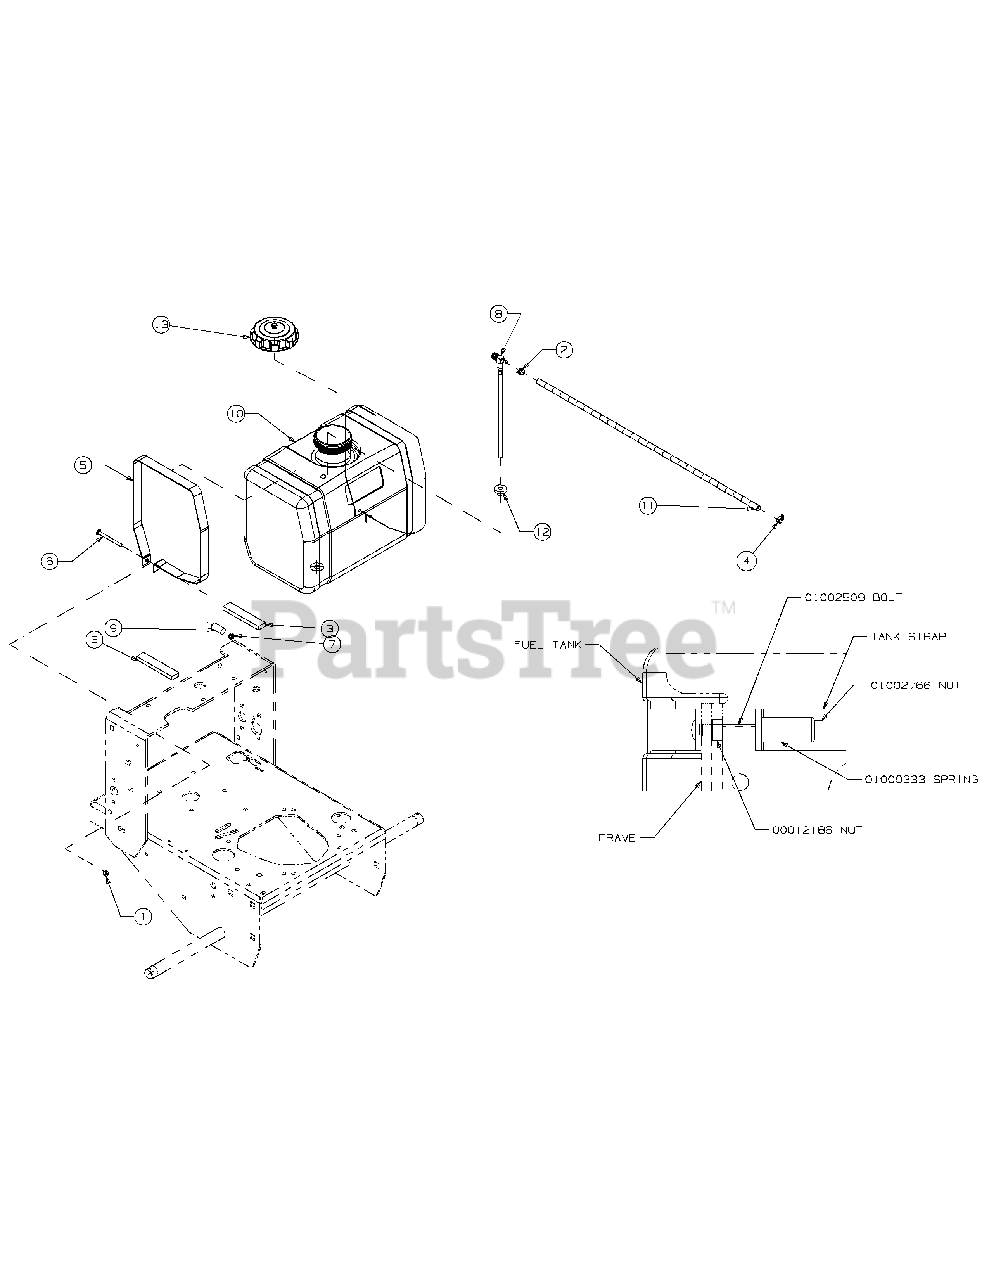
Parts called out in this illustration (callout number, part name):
1	Hex Nut, 1/4-20
2	Uni-Clamp
3	Rubber Stop Pad
4	Hose Clamp, SAE #4: 1/4-5/8, SS
5	Fuel Tank Strap
6	Carriage Bolt, 1/4-20 x 3.00
7	Hex Flange Lock Nut, 1/4-20
8	Shut Off Fuel Tank
9	Spring, .625 OD x .390 ID x 1.20
10	Fuel Tank
11	Hose Fuel, 28" x .25 ID
12	Grommet, Fuel Tank
13	Fuel Cap, 3.5
